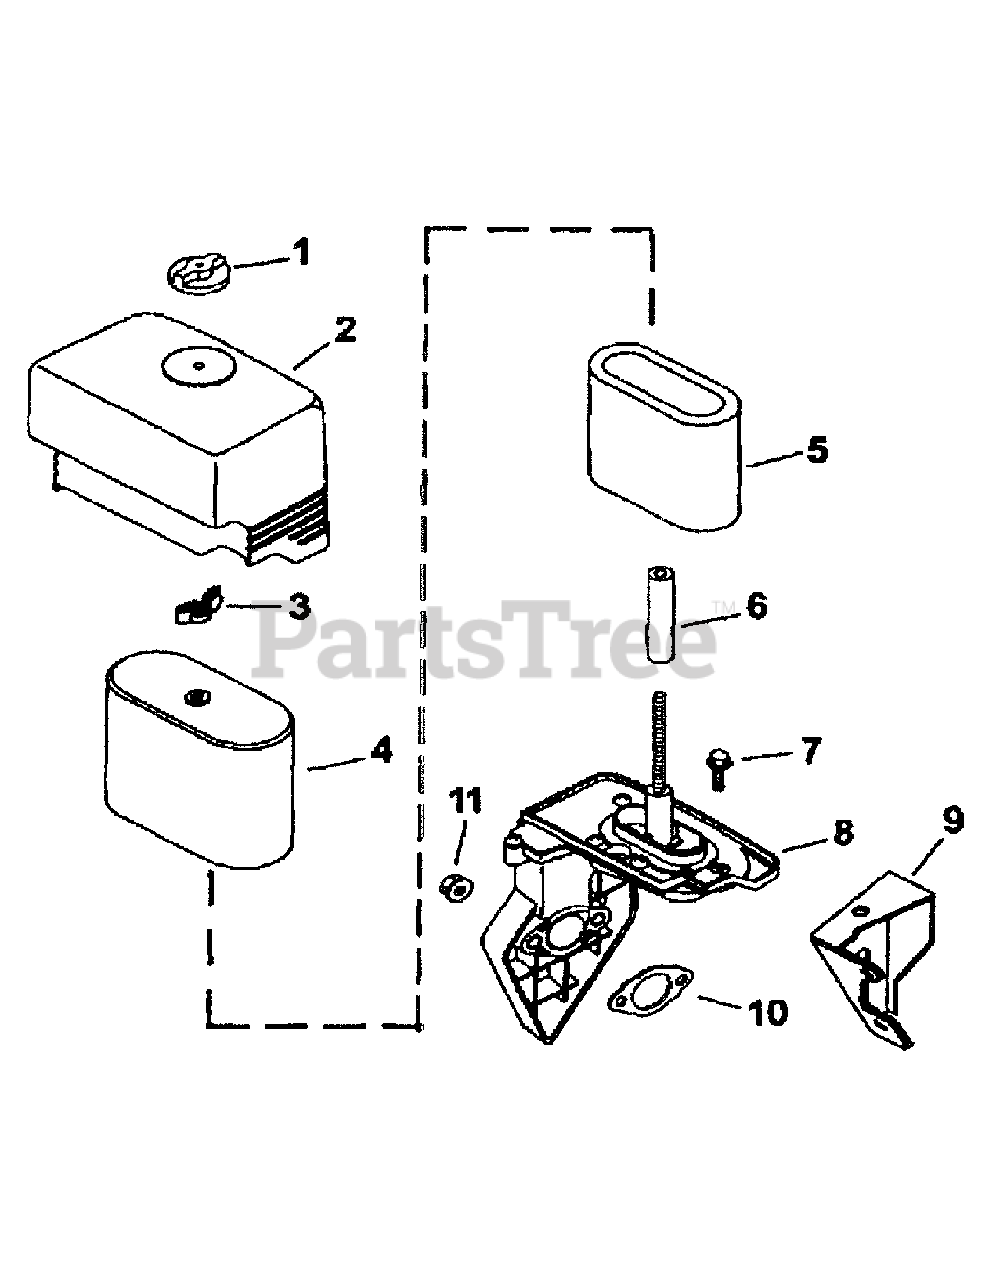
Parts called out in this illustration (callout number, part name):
1	Nut, Air Cleaner
2	Cover, Air Cleaner
3	Nut, Wing
4	Element, Air Cleaner
5	Element, Precleaner
6	Seal, Air Cleaner
8	Base, Air Cleaner
9	Bracket, Air Cleaner
10	Gasket, Air Cleaner
11	Nut, Air Cleaner
